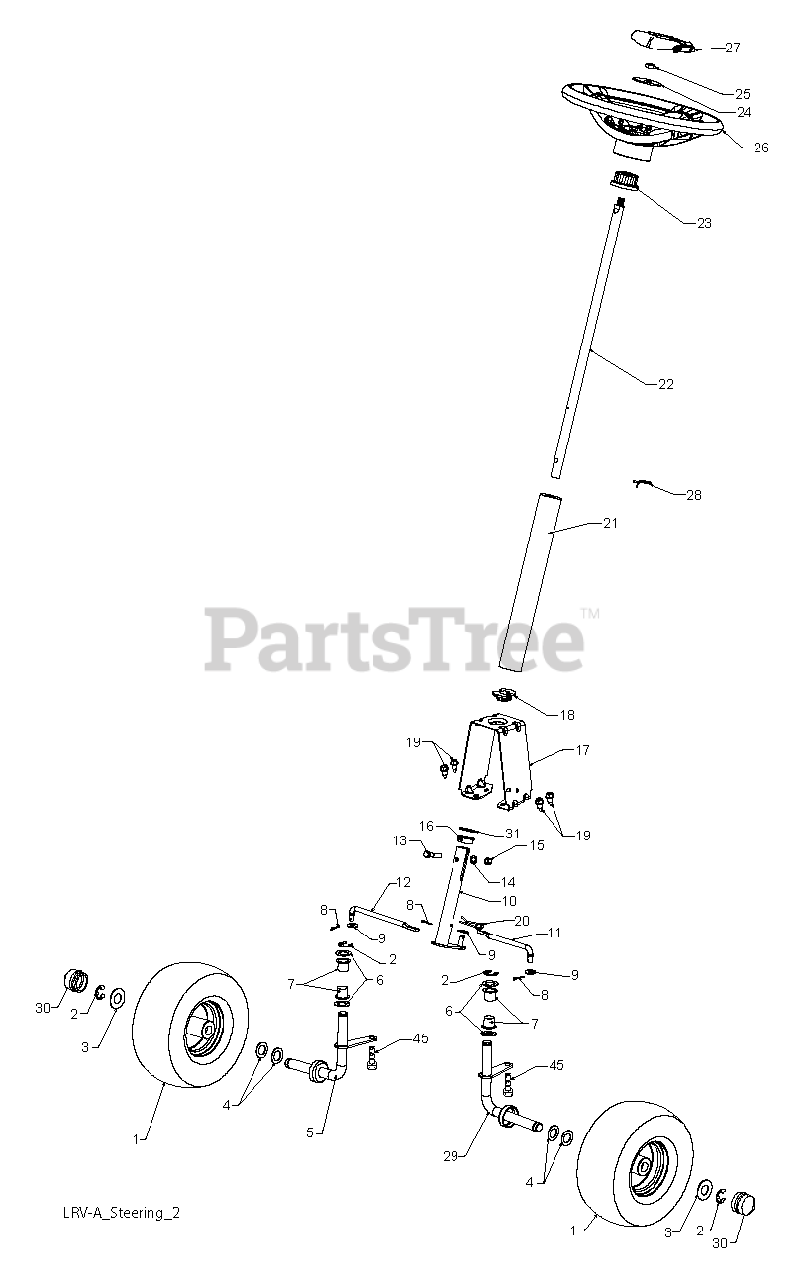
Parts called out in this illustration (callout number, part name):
1	WHEEL.ASM.FRONT.LRV.10" GRAY
2	E-RING LT
3	WASHER.HARDENED
5	SPINDLE.STEERING.RH.LRVA
7	Steering Column Bearing
8	PIN.COTTER.5/64X3/4
10	WELDMENT, LWR STRG SHAFT
11	LINK, STRNG LH LRV
12	LINK.STEERING.RH.LRV
13	HEX BOLT
15	NUT.71038.31-18.HEX.NYLOCK
16	BUSHING, STEERING SNAP
17	SUPPORT, UPPER STEERING
18	BUSHING,STEERING
19	SCREW
20	CLIP.SPRING.STEERINGG
21	FOAM.SHAFT.STEERING
22	SHAFT, STEERING
23	STEERING.WHEEL.ADAPTER
24	WASHER 9/16"ID, 2 3/8""OD
25	NUT.HEX.1/2-20
26	WHEEL.STEER.STDR.498.OVRM.GRAY
27	CAP.WHL.STRNG.STDSRRD.SRS.GREY
28	RETAINER.CLIP.SPRING.S
29	WELDMENT.SPINDLE.LH.LR
30	CAP.HUB.AXLE.LRVA/B
45	BOLT.SHOULDER.5/16-18X
